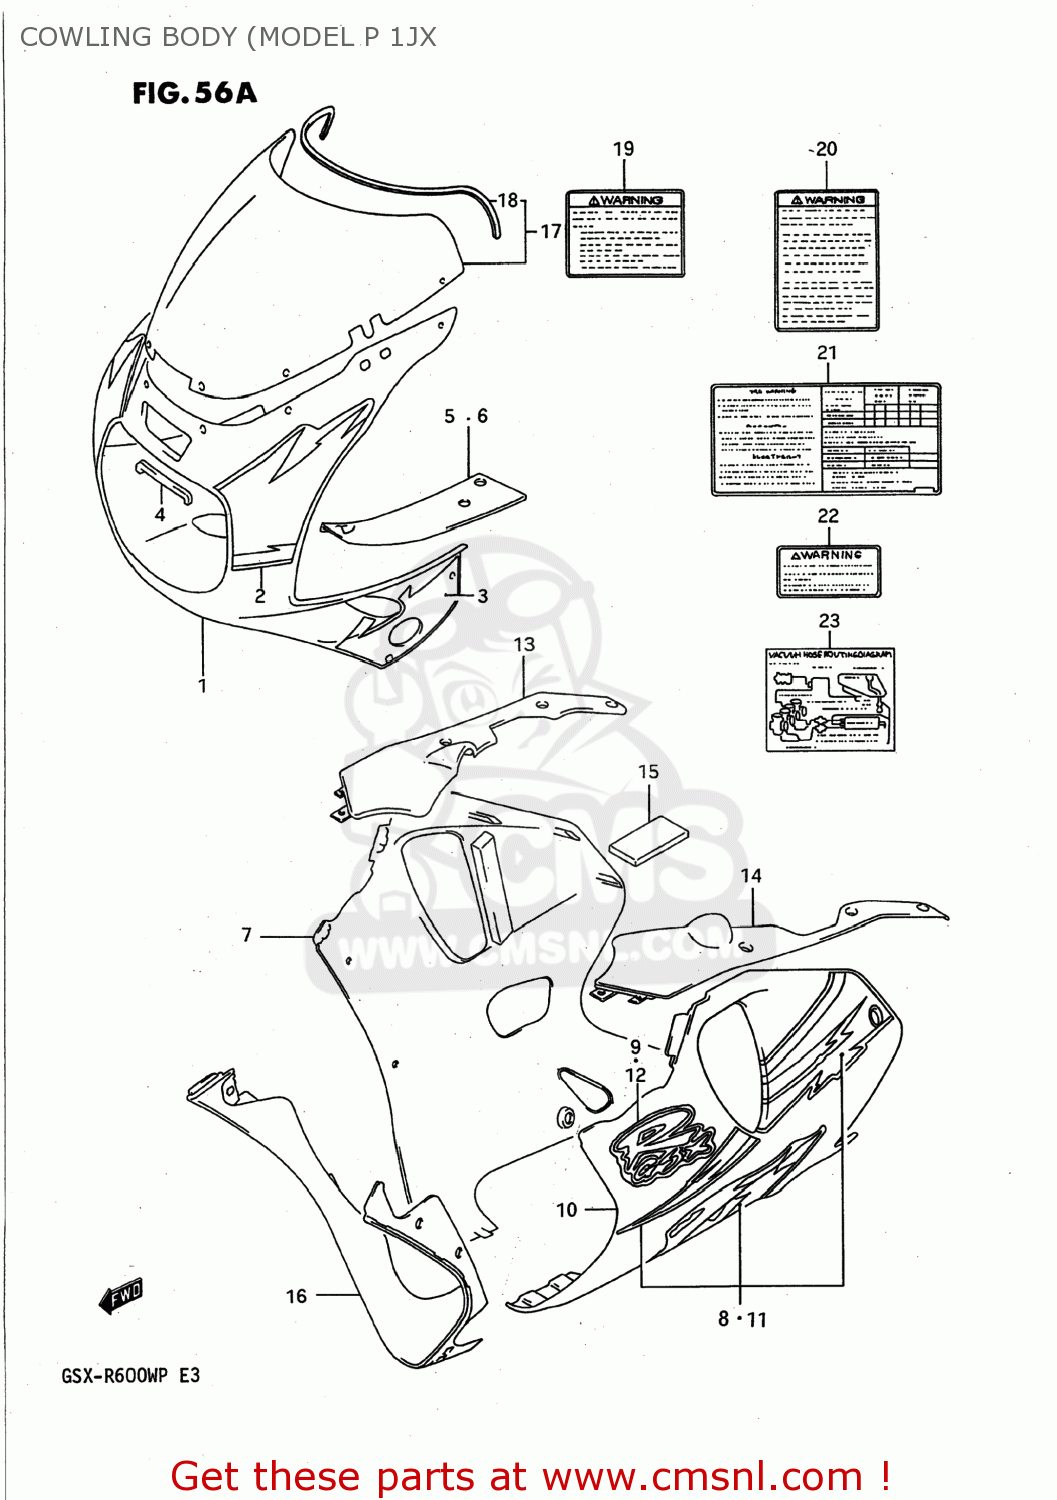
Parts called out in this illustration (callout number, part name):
1	COWLING ASSY,BODY
2	TAPE SET,COWLING BODY,FRONT
3	TAPE SET,COWLING BODY
4	CUSHION,FR POSITION LAMP
5	PANEL,UPR,R
6	PANEL,UPR,L
7	COWLING ASSEMBLY,UNDER,RIGHT
8	TAPE SET,COWLING,UNDER
9	EMBLEM,COWLING,UNDER
10	COWLING ASSEMBLY,UNDER,LEFT
11	TAPE SET,COWLING,UNDER
12	EMBLEM,COWLING,UNDER
13	PANEL,LWR,R
14	PANEL,LWR,L
15	CUSHION,PANEL
16	COWLING,UNDER CTR
17	WINDSCREEN SET
18	MOLDING
19	LABEL
20	LABEL (WARNING SCREEN)
21	LABEL (TIRE AIR PRESSURE)
22	LABEL,WARNING STEERING
23	LABEL (VACUUM HOSE ROUTING)
